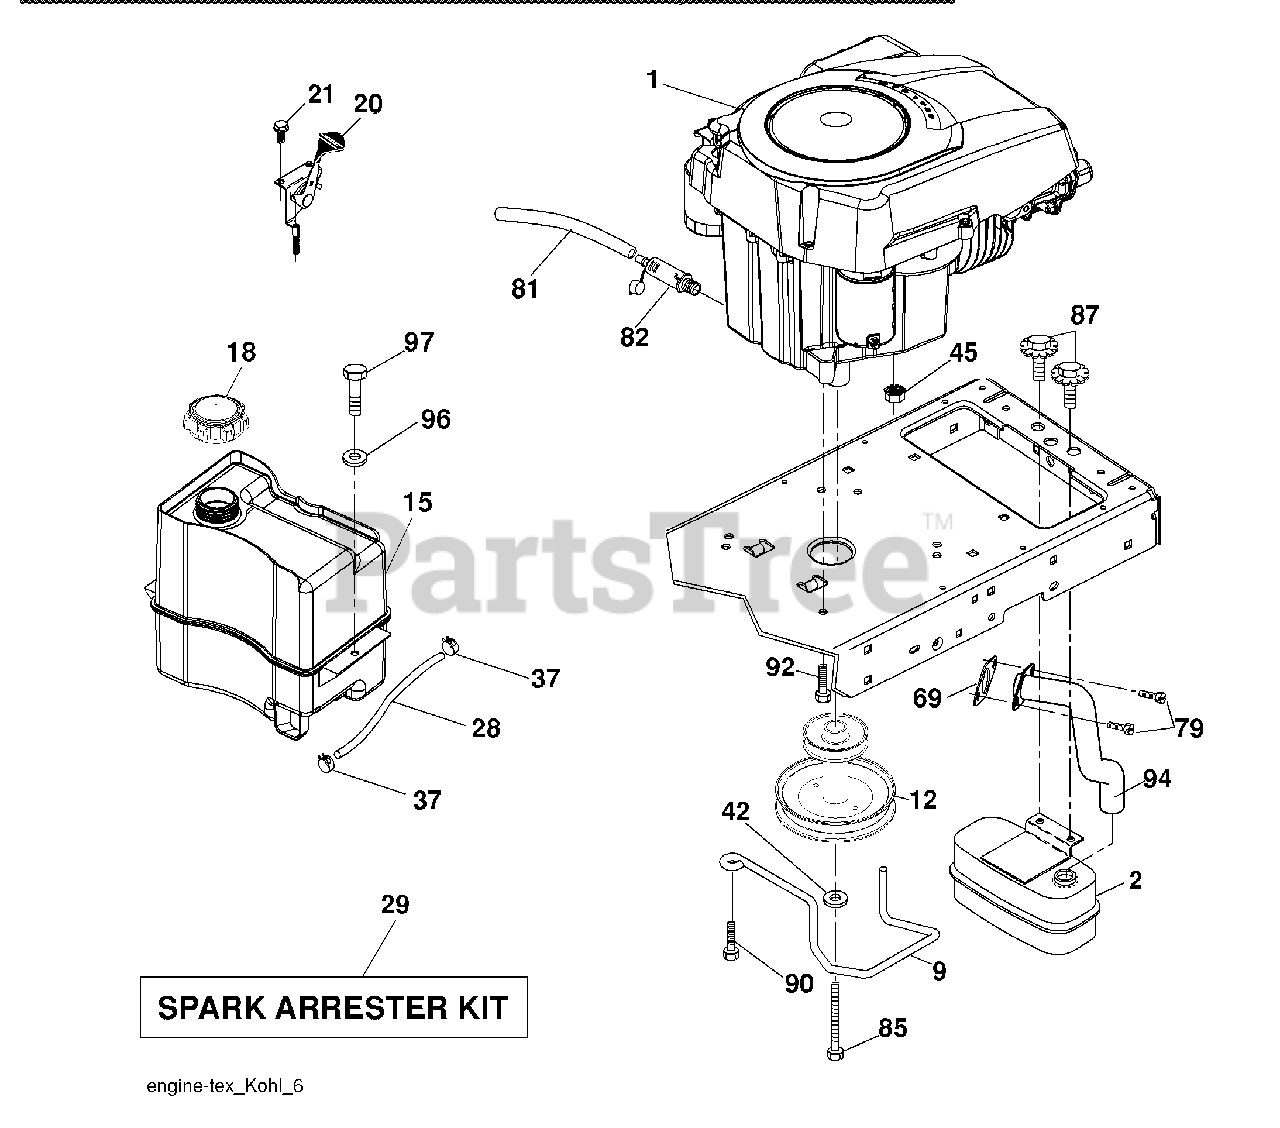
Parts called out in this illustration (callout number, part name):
9	Keeper Belt Engine
12	Pulley Engine
15	Tank Fuel
18	Cap Asm
20	Control Throttle
21	Screw #10 x 0.750
28	Fuel Line
29	Spark Arrester Kit
37	Clamp Hose
42	Washer Lock 7/16
45	Nut Keps Hex 1/4-20 unc
79	Screw Socket Hd. 5/16-18 x .75
81	Tube Drain Oil Easy
82	Plug Drain Oil
85	Bolt Hex 7/16-20 x 4 x Gr. 5-1.5 Thr
87	Bolt 5/16-18 unc x 3/4 w/Sems
90	Screw 3/8-16 x 1
92	Screw 3/8-16 x 1
94	Tube Exhaust
96	Washer 9/32 x 7/8 x 16 Ga.
97	Screw 1/4-20 x 3/4
